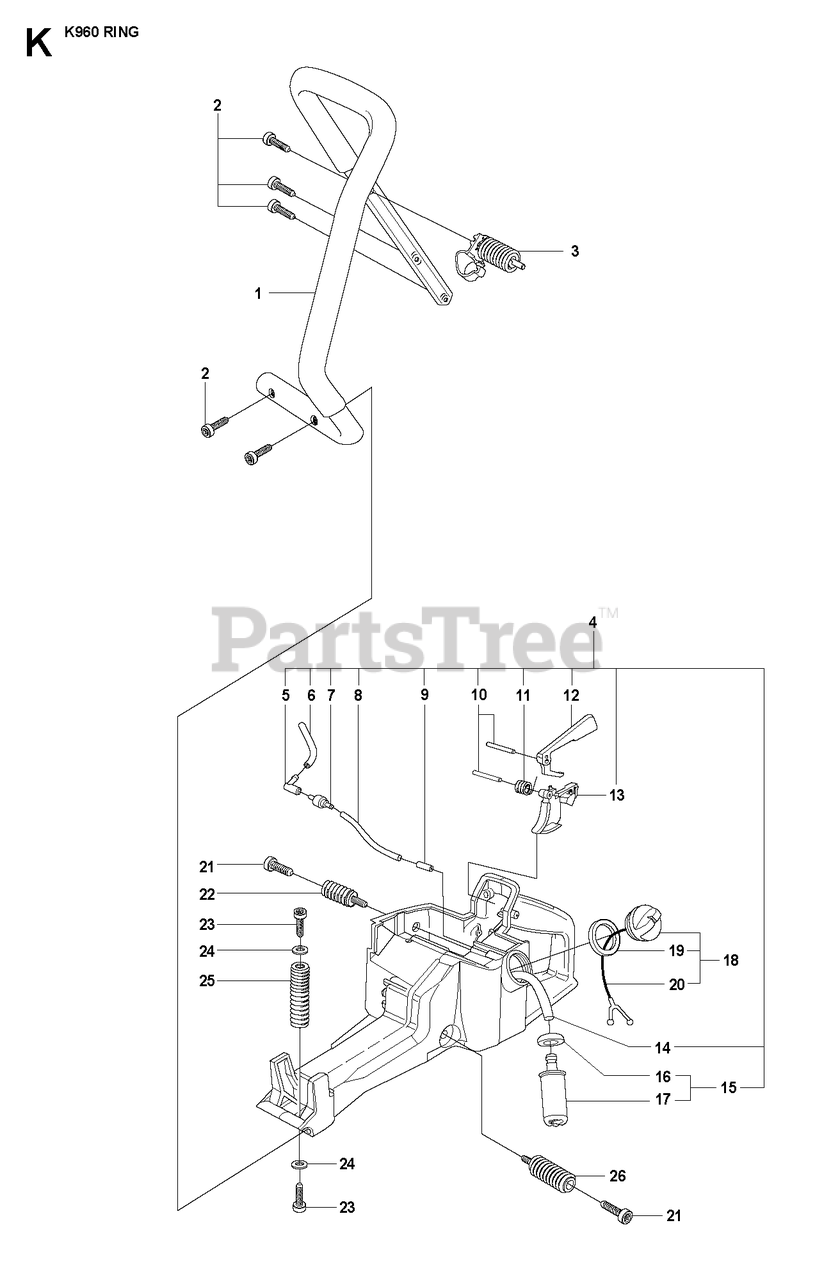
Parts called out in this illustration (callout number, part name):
2	SCREW ITXSCT
3	ANTIVIBRATION ELEMENT
4	FUEL TANKIncl. 5 - 15
5	CONNECTION BEND
6	FUEL HOSE
8	FUEL HOSE
10	PARALLEL PIN
11	SPRING THROTTLE TRIG
12	THROTTLE LOCKOUT
14	FUEL HOSE
15	FUEL FILTERIncl. 16, 17
18	TANK CAP ASSYIncl. 19, 20
21	SCREW ITXSCM
22	ANTIVIBRATION ELEMENT
23	SCREW ITXSCM
25	ANTIVIBRATION ELEMENT
